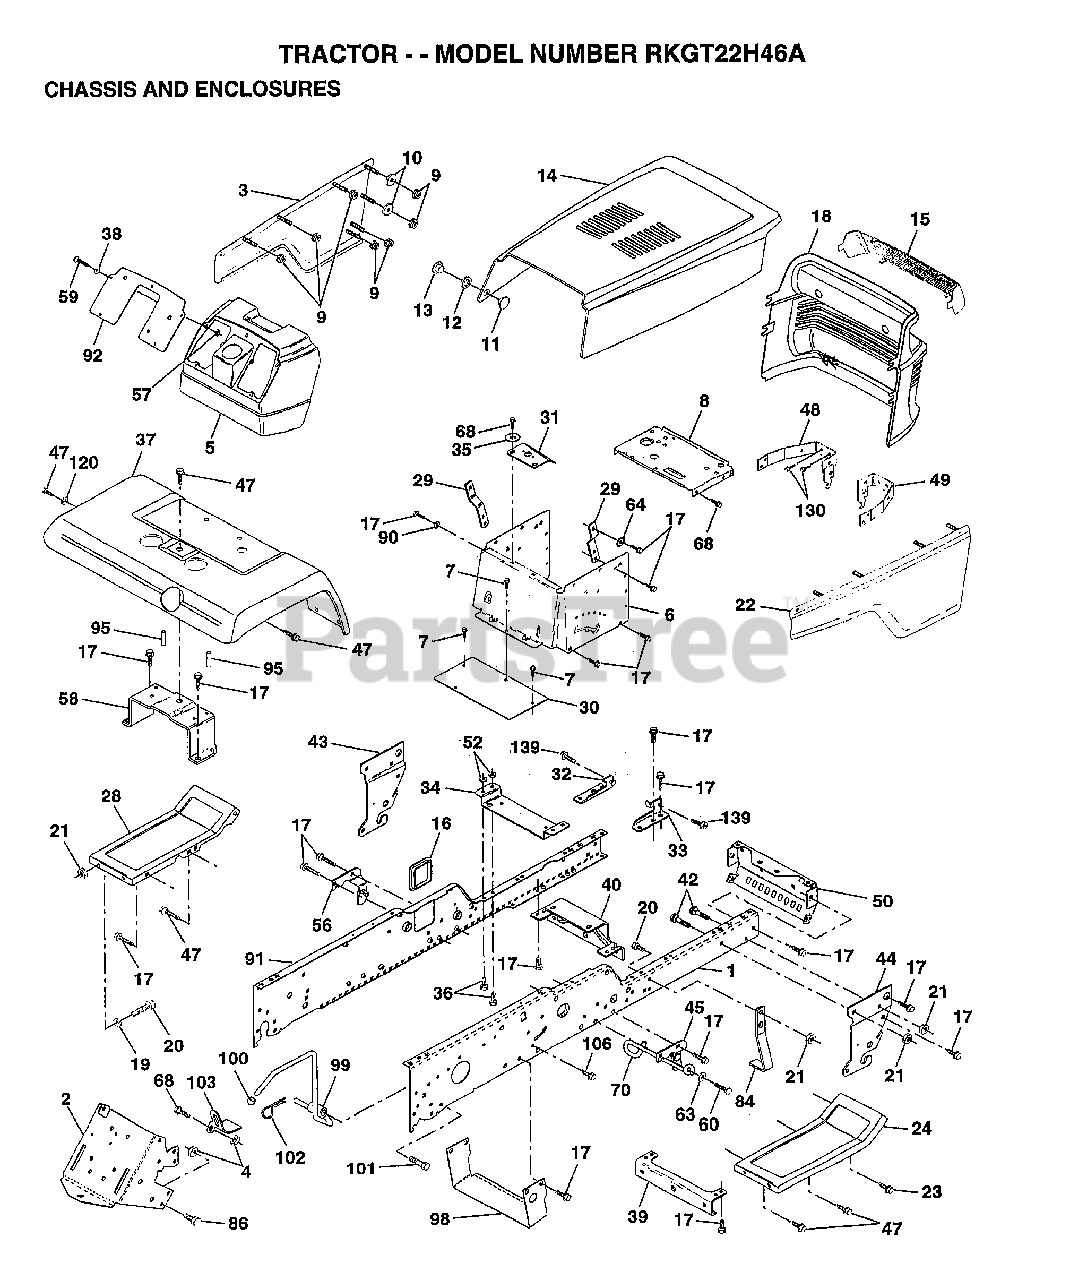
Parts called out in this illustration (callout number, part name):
1	"RAIL,FRAME RH"
2	DRAWBAR GT
3	PANEL.ASM.SIDE.LHG
4	NUT GTV
5	DASH.PLASTIC.BLK
6	DASH LOWER
7	SCREW
8	SUPPORT.DASH.BTRY
9	PAL NUT LT
10	WASHER
11	RIVET.RATCHET.MAL
12	WASHER.NYLON
13	RIVET.RATCH.FEMAL
14	HOOD.ASM.PNT
15	LENS.YT.GT.SEARS
16	COVER ACCESS
17	SCREW
19	WASHER
20	BOLT
21	NUT
22	PANEL ASM, SIDE RH
23	SCREW GTV
24	FOOTREST.RH.LT/GT
28	FOOTREST PNT LH
29	BRACKET.SUPT.DASH
30	SADDLE.HYDRO.95
31	BRKT SUPT 1-PC VG
32	BKRT.PIVOT.CHASSIS.LH
33	BKRT.PIVOT.CHASSIS.RH
34	BRACKET.ENG.SUPT.
35	WASHER
36	BOLT
37	"FENDER WS,FTK"
38	WASHER PM
39	BRACKET.AXLE.FRT.
40	"BRKT SUPPORT,AXLE"
43	BRACKET.SUS.FT.LH
44	BRACKET.SUS.FT.RH
45	BRACKET.SUSP.RH.
47	SCREW LT
48	BRKT ASM PIVOT LH
49	BRKT ASM PIVOT RH
50	"BRKT CHASSIS,FRNT"
56	BRACKET.SUSP.LH.
57	NUT HXKEP 1/4X20
58	BRKT.ASM.FENDER
59	SCREW
60	SCREW
63	WASHER
64	WASHER.SERRATED.
68	SCREW LT
70	GUIDE.BELT.MID.SP
84	STOP.OVER.CENTER
86	BOLT
90	LOCKWASHER
91	"RAIL FRAME,LH"
95	NUT-PUSH YT
98	BRACKET SKID CHAS
99	ROD BYPASS
101	SCREW LT
102	RETAINER M
103	LOCK BYPASS BRKT
120	WASHER HYT
130	"SCREW,HWHD.HI-LO#13-16X3/4"
139	BOLT.SHOULDER.5/16-18
